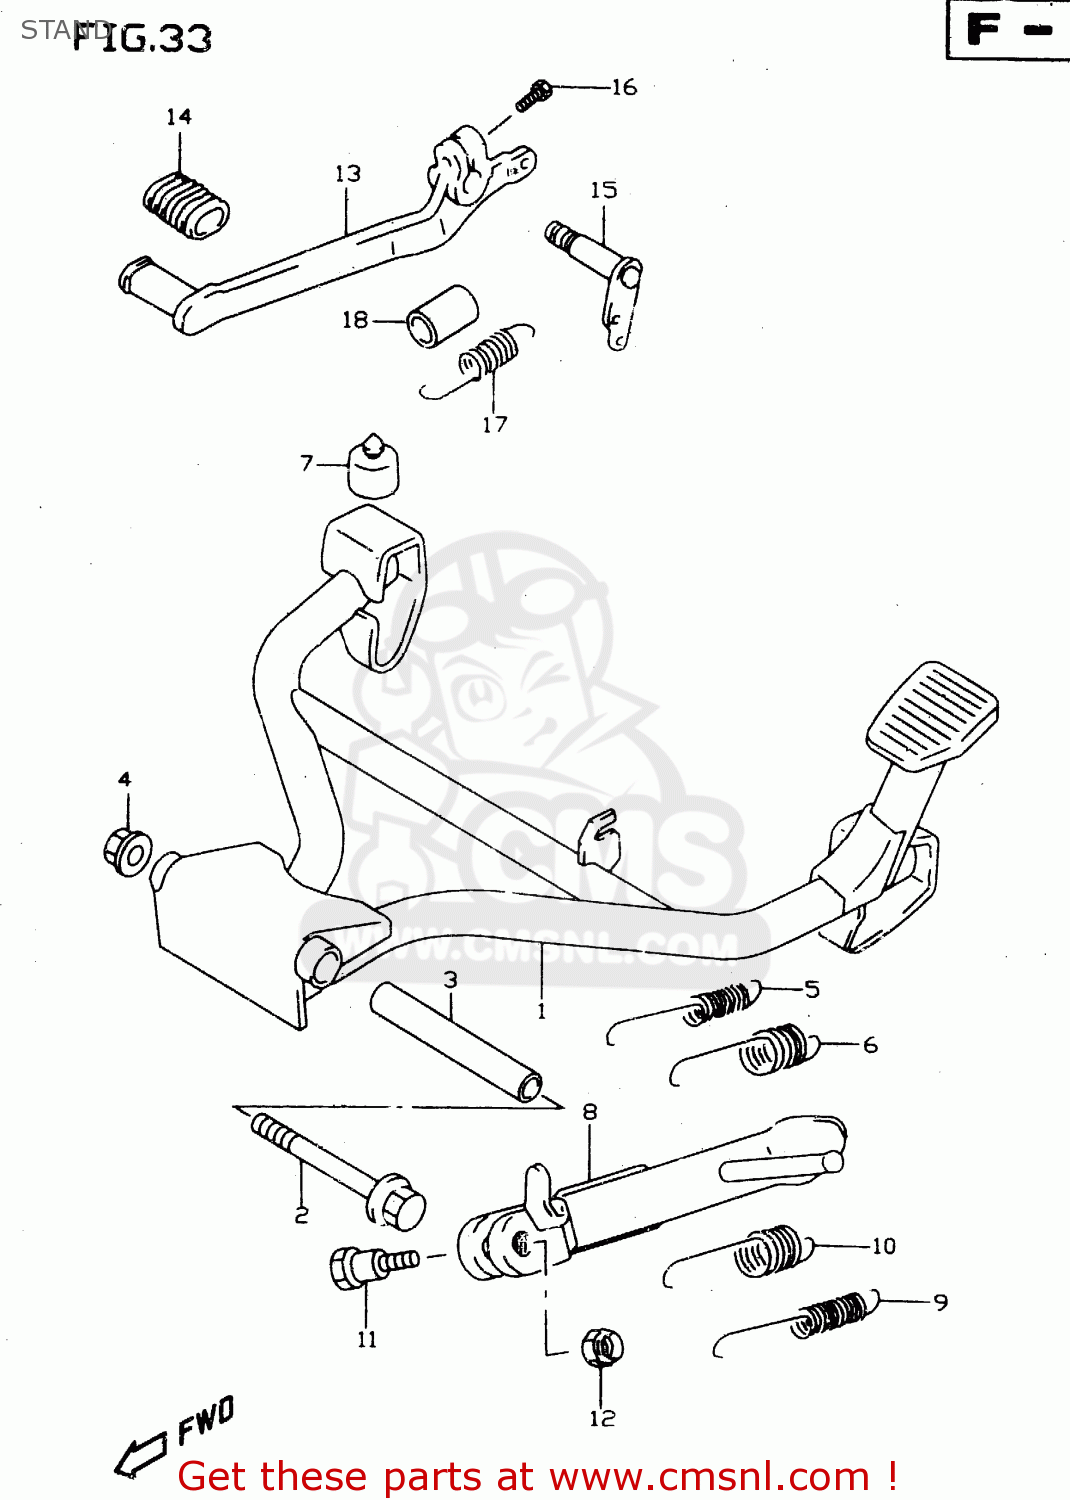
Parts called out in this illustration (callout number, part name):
1	STAND SET,CTR
2	BOLT(10X118)
3	SPACER(10.2X19X95.5)
4	NUT
5	SPRING
6	SPRING OUTER
7	CUSHION
8	STAND,PROP
9	SPRING
10	SPRING
11	BOLT(10X34)
12	NUT
13	PEDAL,BRAKE
14	RUBBER,PEDAL
15	ARM,BRAKE PEDAL ROD
16	BOLT
17	SPRING
18	TUBE,BRAKE SPRING GUIDE
